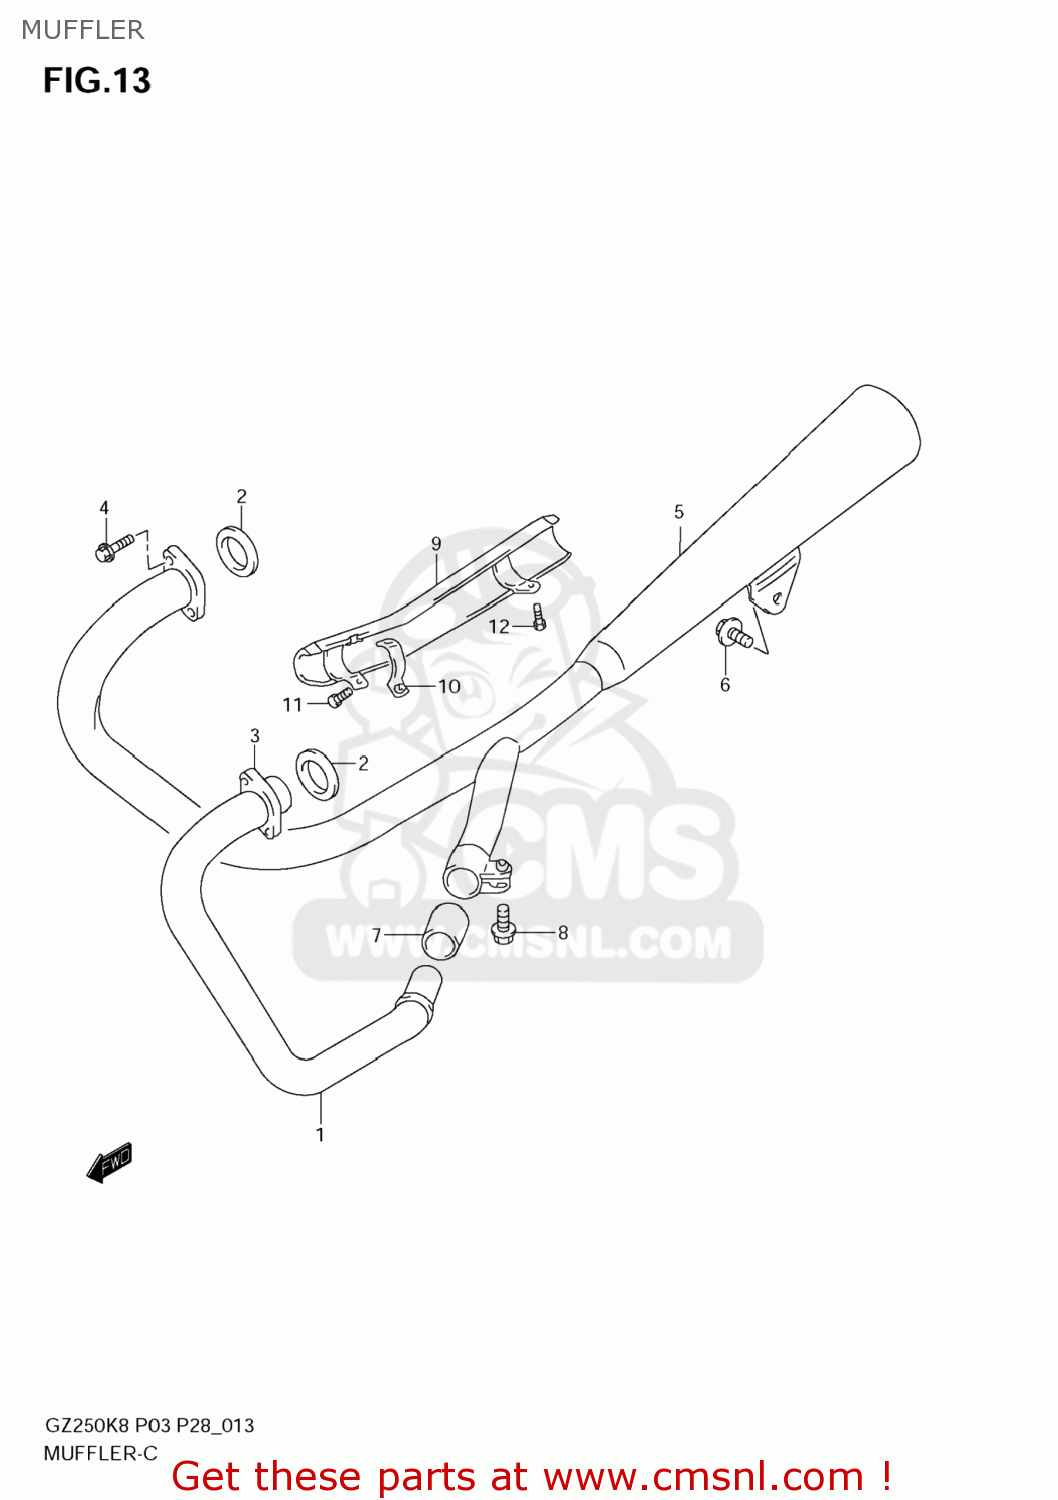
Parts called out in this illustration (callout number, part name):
1	PIPE,EXHAUST,L
2	GASKET,EXHAUST PIPE (NAS)
3	CLAMP,EXHAUST PIPE,L
4	BOLT(6X25)
5	MUFFLER
6	BOLT
7	CONNECTOR,MUFFLER
8	BOLT
9	COVER,MUFFLER
10	CLAMP,MUFFLER COVER
11	SCREW
12	SCREW
